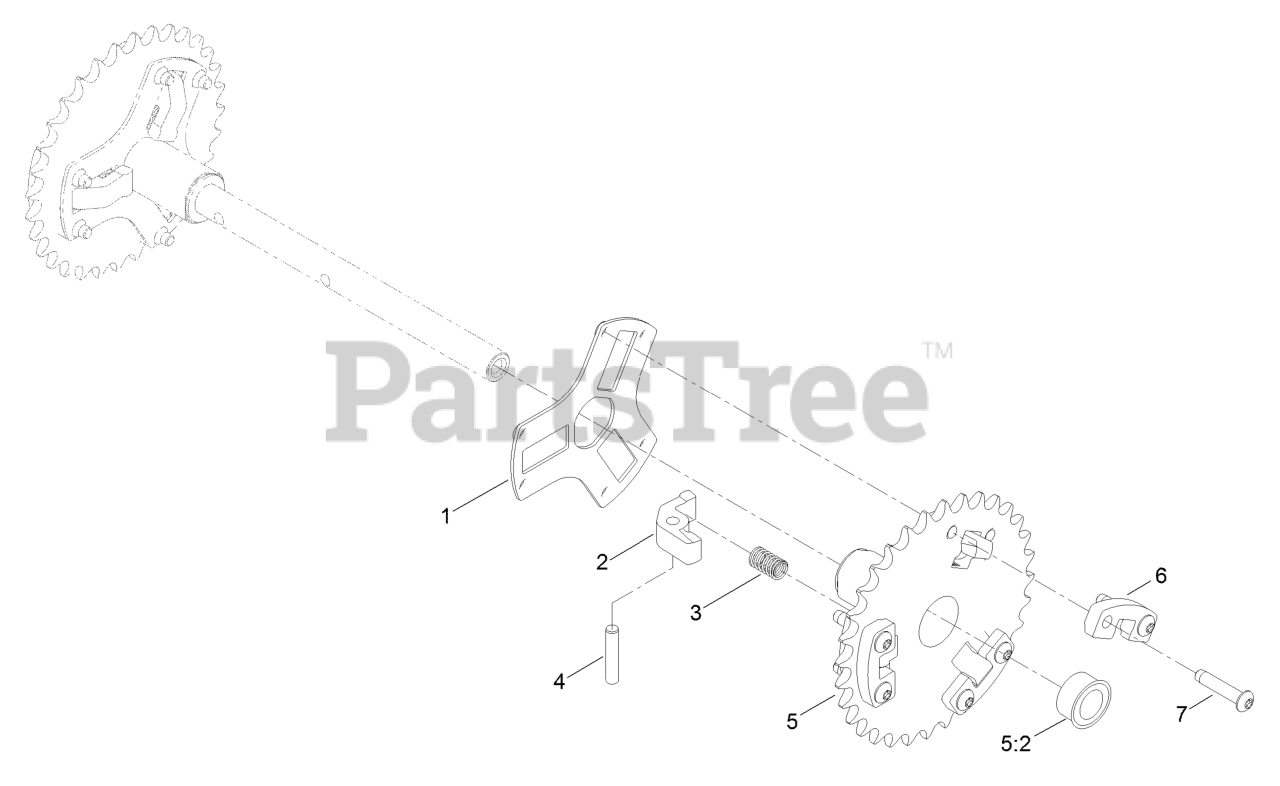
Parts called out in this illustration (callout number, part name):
1	RETAINER-PIN, PAWL
2	PAWL-CLUTCH
3	SPRING-COMPRESSION
4	PIN-DOWEL
5	32T SPROCKET ASM
5:2	BUSHING-FLANGE
6	SUPPORT-PAWL
7	SCREW-TTH, THREAD ROLLING
